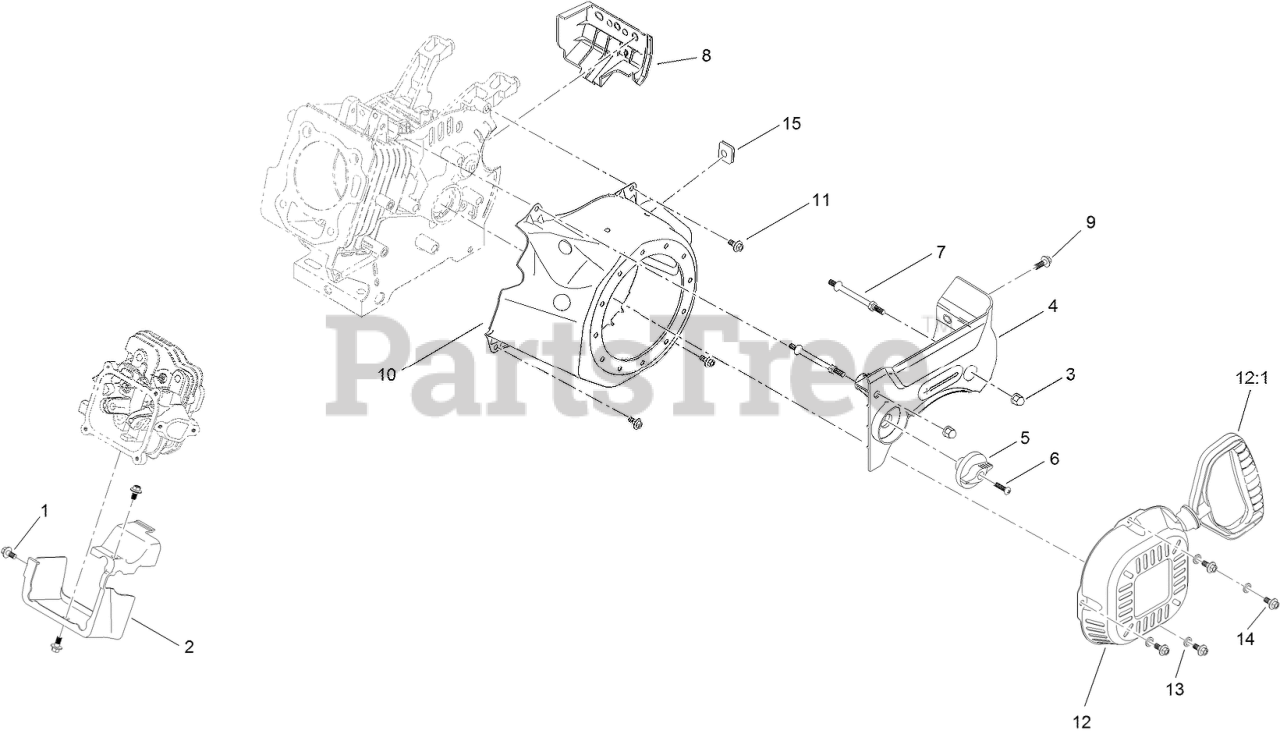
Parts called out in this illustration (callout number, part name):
1	SCREW-HHF
2	SHROUD-HEAD
3	NUT-ACORN
4	PANEL-CONTROL, FRONT
5	KNOB-VALVE, FUEL
6	SCREW-BHP
7	STUD-MOUNT
8	PANEL-SIDE, ENGINE
9	SCREW-HHF
10	SHROUD-FLYWHEEL
11	SCREW-HHF
12	RECOIL ASM
12:1	HANDLE-RECOIL
13	WASHER-PLAIN
14	SCREW-HHF
15	GROMMET-RUBBER
